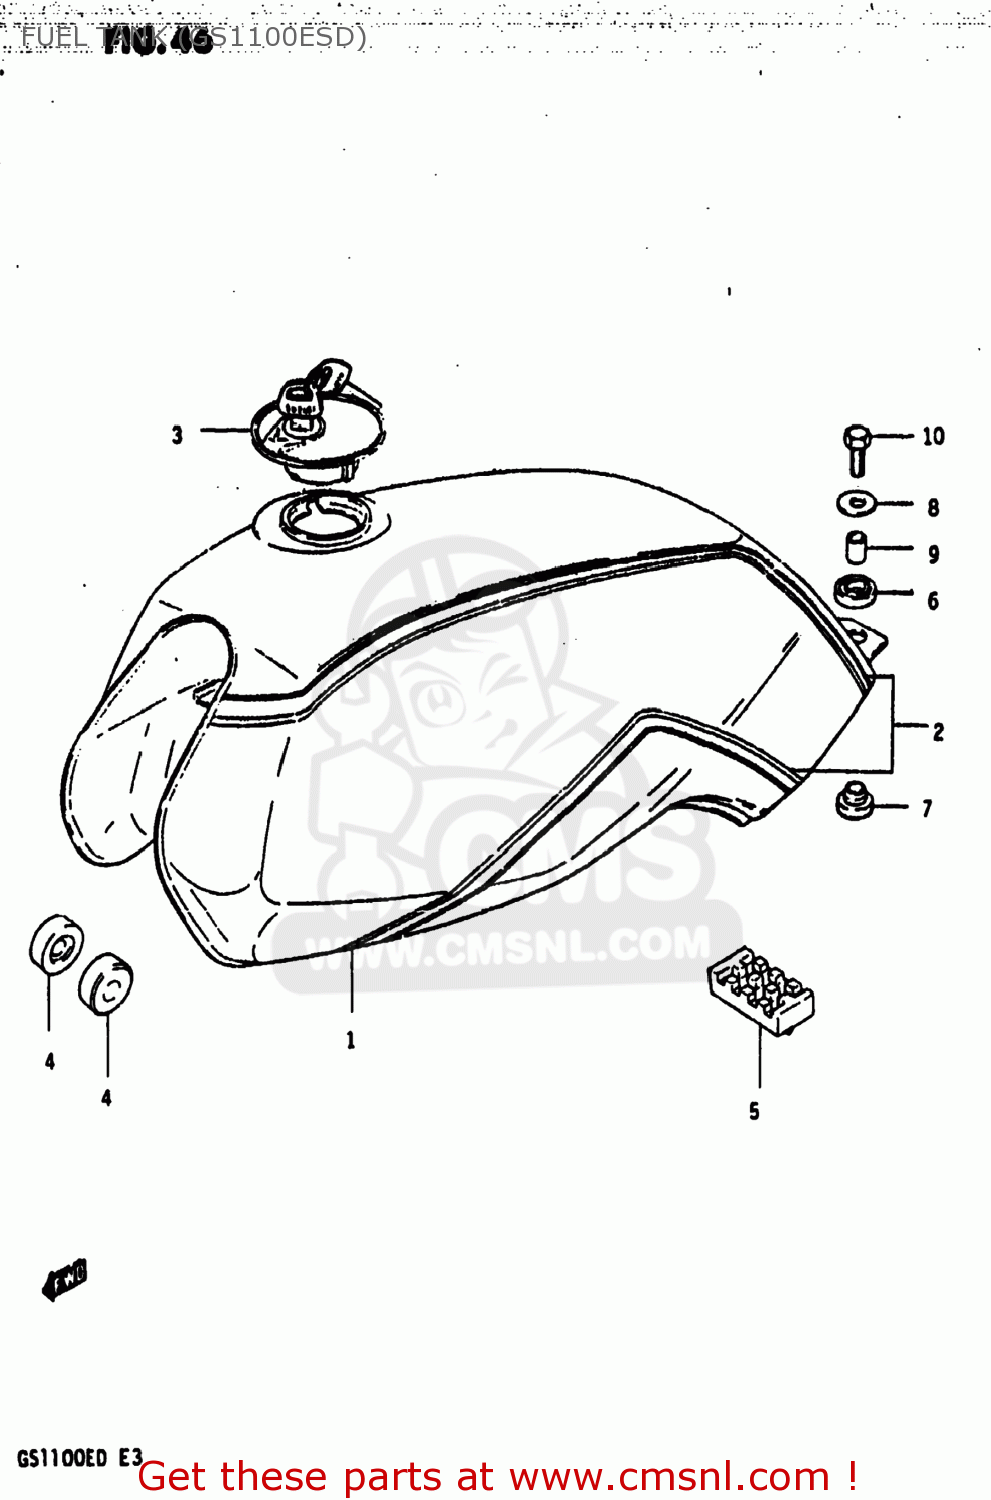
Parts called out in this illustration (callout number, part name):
1	TANK ASSEMBLY,FUEL
2	TAPE SET,FUEL TANK
3	CAP SET,FUEL TANK
4	CUSHION
5	CUSHION,FUEL TANK CTR
6	CUSHION
7	CUSHION
8	WASHER (6.5X24X1.6)
9	SPACER
10	BOLT
